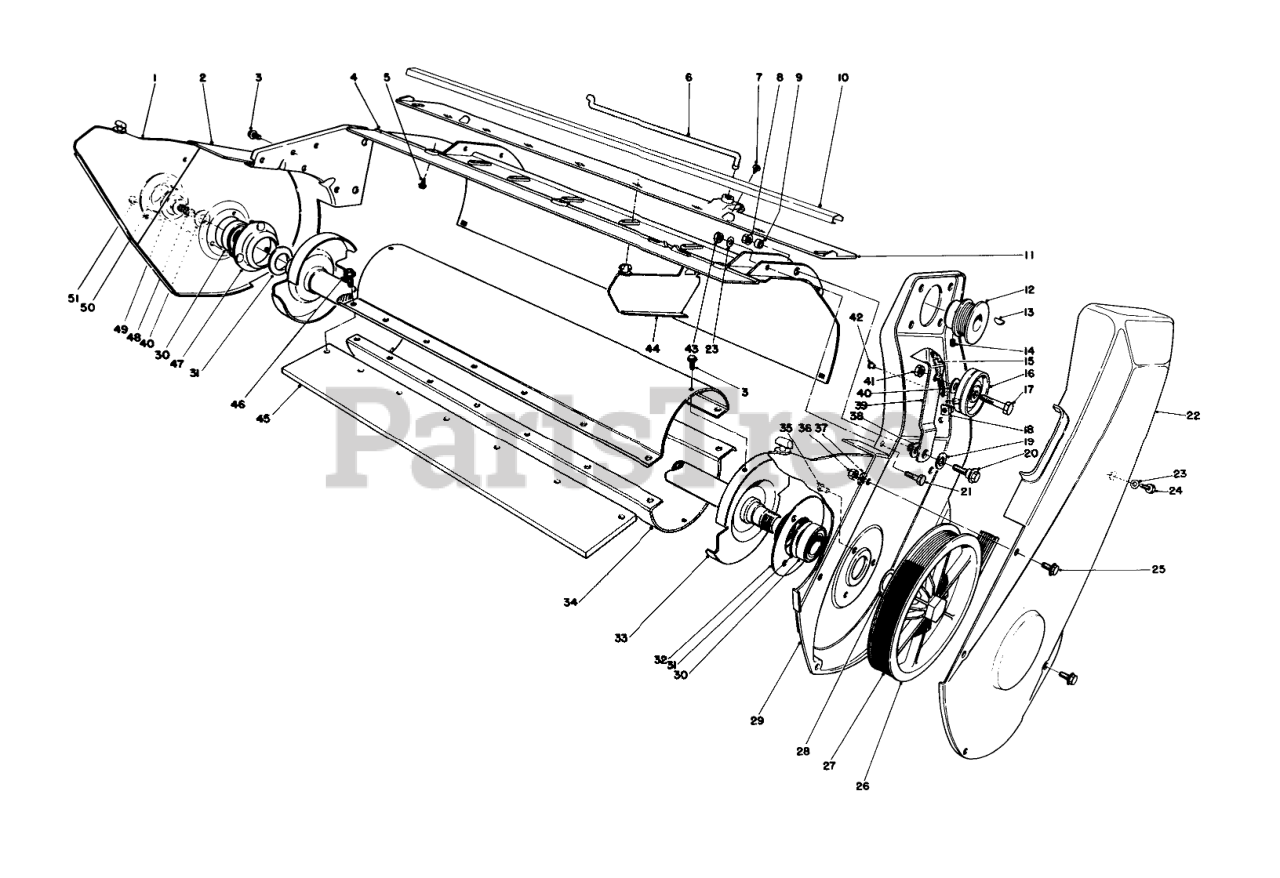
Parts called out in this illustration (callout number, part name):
1	OUTSIDE VANE
2	Plate-R.H. Side
3	SCREW-HWH
4	HOUSING ASSEMBLY
5	SCREW-HWHTF
6	VANE ADJ LINKAGE
7	10-16 X 3/8 THDG SCREW
8	NUT-HF
9	SPACER
10	Molding
11	Mount-Vane
12	Pulley
13	KEY-WOODRUFF
14	SCREW-HSH
15	IDLER SPRING
16	IDLER PULLEY
17	SCREW-HH
18	TINNERMAN NUT
19	WASHER
20	SCREW-SHOULDER
21	SCREW-HH
22	Cover-Drive
23	WASHER-FLAT
24	SCREW-HEX HD
25	SCREW-SHWH
26	PULLEY ASM ROTOR
27	BELT - DRIVE
28	WASHER
29	Plate-L.H. Side
30	BEARING-BALL
31	WASHER-THRUST
32	FLANGE-BEARING
33	END CAP WA
34	ROTOR SHELL
35	RIVET
36	NUT-LOCK, NI
37	WASHER-FLAT
38	WASHER-PIVOT
39	IDLER ARM
40	WASHER-FLAT
41	NUT-LOCK, NI
42	Eyelet
43	NUT-LOCK, CONE
44	CENTER VANE
45	ROTOR BLADE
46	Screw
47	FLANGE-BEARING
48	SCREW-HHF
49	WASHER-RUBBER
50	Trough
51	NUT-CAP
